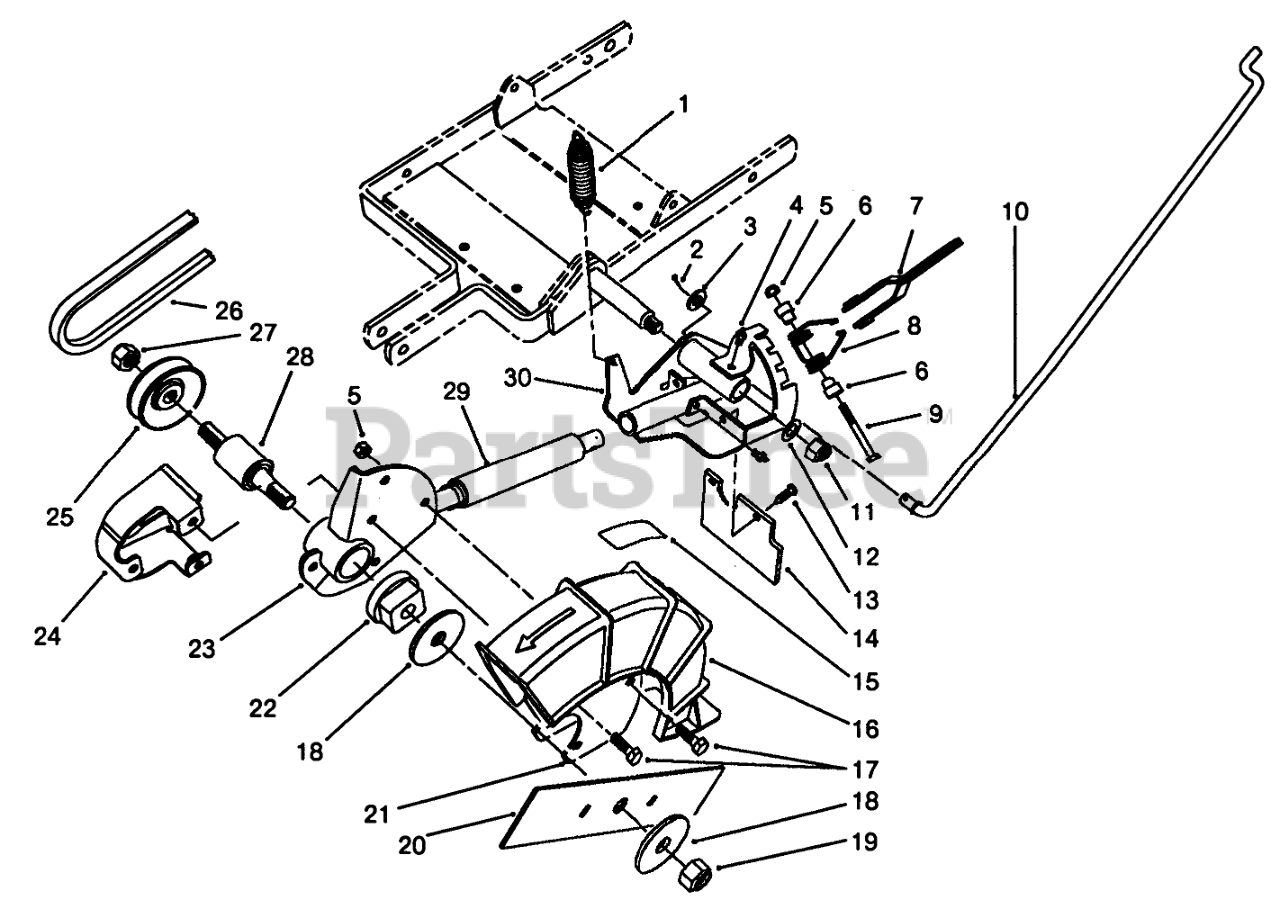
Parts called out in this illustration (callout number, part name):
1	EXT. SPRING
2	PIN-COTTER
3	WASHER-FLAT
4	FITTING-GREASE
5	NUT-LOCK, NI
6	SPACER-PIVOT LEVER
7	LEVER WA
8	TORSION SPRING
9	SCREW-HH
10	LOWER CONTROL ROD
11	NUT-LOCK, NI
12	WASHER-PLAIN
13	PANEL FASTENER
14	RUBBER GUARD
15	Decal-Warning
16	Blade Guard Assembly (Incl. Ref. #15)
17	SCREW-HWHTF
18	WASHER-LARGE
19	NUT-HEX
20	10" EDGER BLADE B
21	GUARD PLATE
22	BRG SHIELD
23	HUB ASM
24	PULLEY GUARD WA
25	PULLEY
26	V-BELT
27	NUT-LOCK, NI
28	SPINDLE ASM
29	SPRING & BELLOW ASM
30	PIVOT ARM WELDMENT B
